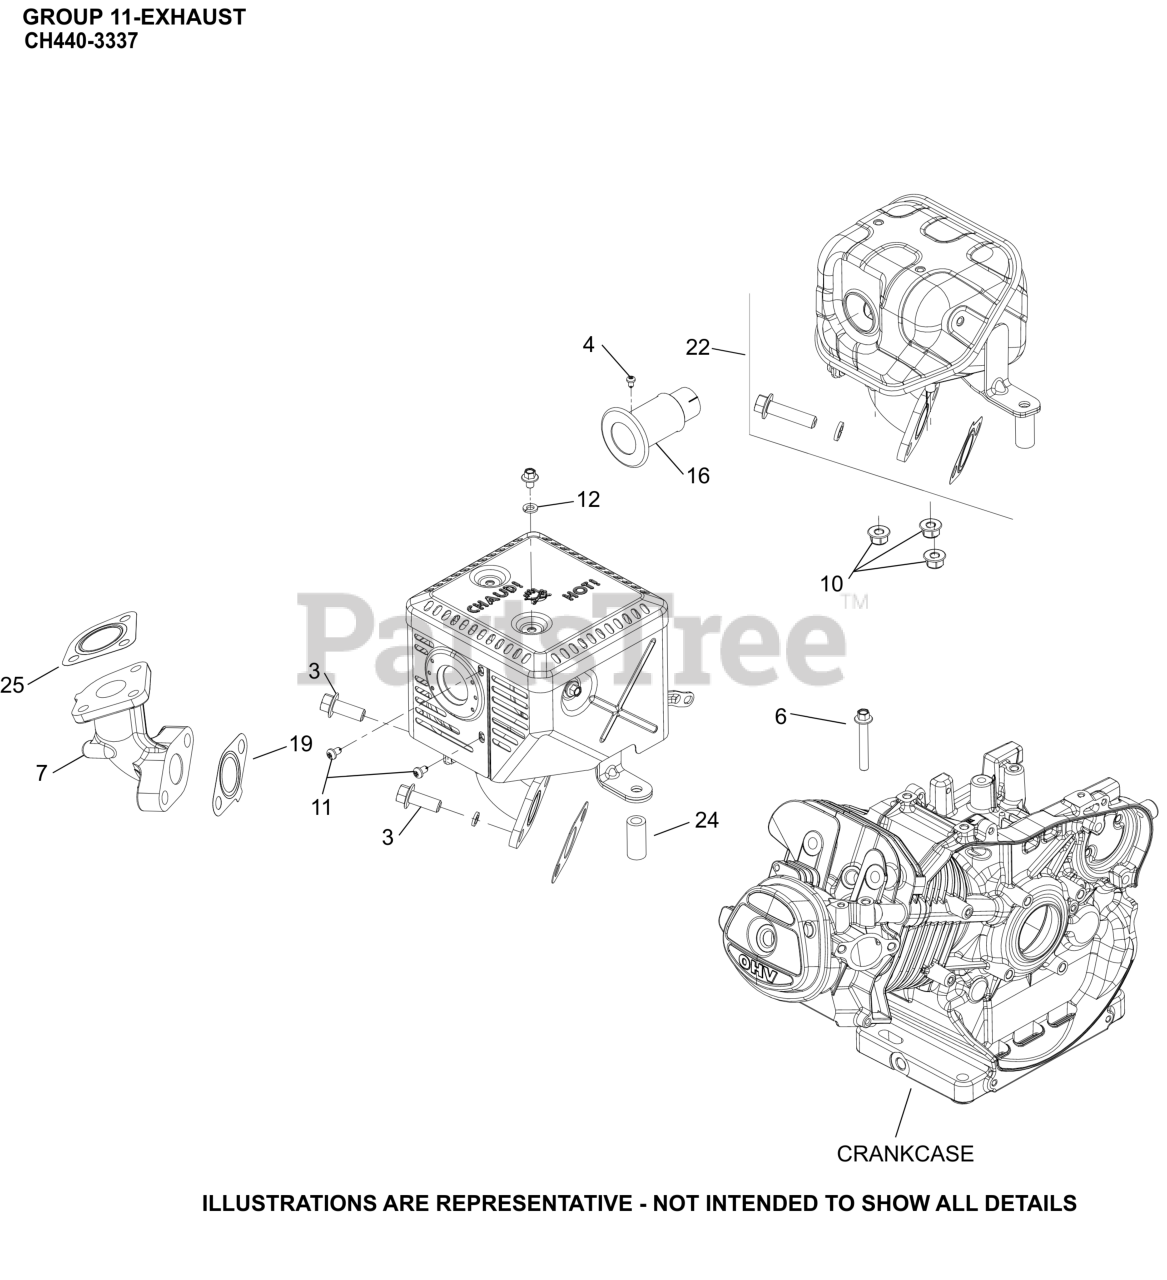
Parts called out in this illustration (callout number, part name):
3	SCREW, M10 X 40
4	SCREW, SPARK ARRESTOR
6	SCREW, M8 X 55
7	ELBOW, EXHAUST
10	NUT, HEX FLANGE LOCK (M8)
11	SCREW, M5 X 8, HEX FLANGE HEAD
12	WASHER, LOCK
16	ARRESTOR ASSEMBLY, SPARK
19	GASKET, EXHAUST
22	MUFFLER ASSY, WITH SHIELD
24	POST, MUFFLER BRACKET
25	GASKET, MUFFLER
